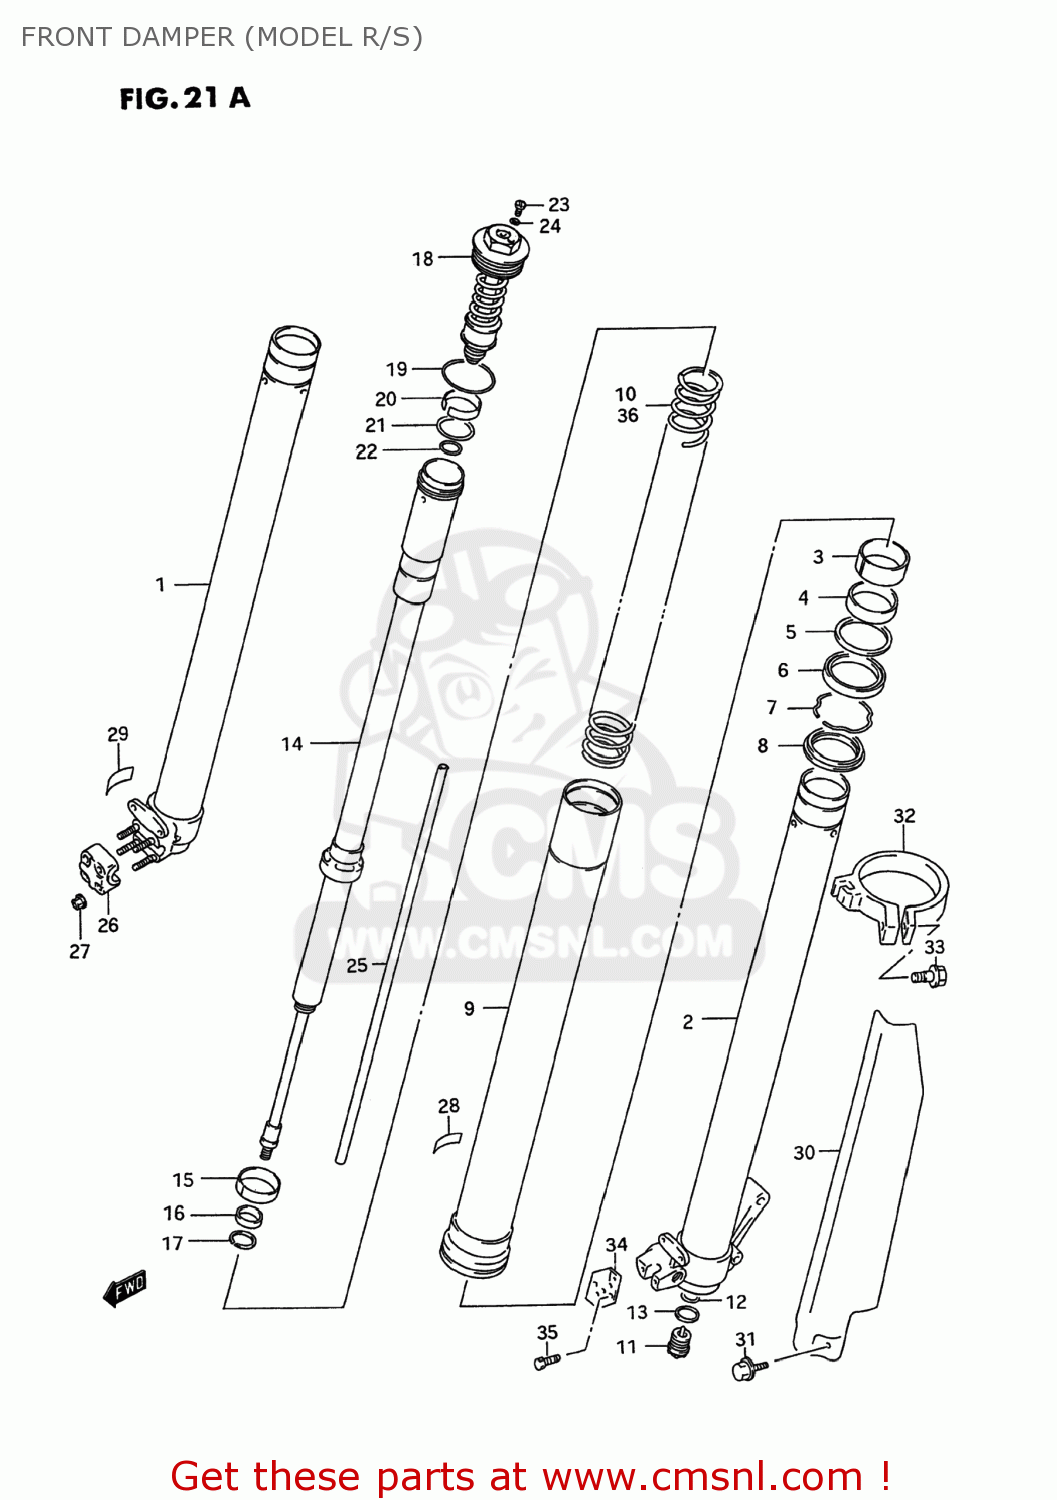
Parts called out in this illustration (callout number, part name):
1	TUBE,INNER,RIGHT
2	TUBE,INNER,LEFT
3	BUSH,SLIDE
4	BUSH,GUIDE
5	SPACER,SEAL
6	SEAL,OIL
7	RING,OIL SEAL STOPPER
8	SEAL,DUST
9	TUBE,OUTER
10	SPRING,MAIN
11	BOLT,CTR
12	GASKET (NAS)
13	O RING,CTR BOLT
14	DAMPER,CARTRIDGE
15	BUSH,DAMPER SLIDE
16	VALVE,OIL LOCK
17	RING,VALVE STOPPER
18	BOLT,FORK
19	O RING
20	BUSH,FORK BOLT SLIDE
21	O-RING,FORK BOLT,CENTER
22	O-RING,FORK BOLT,LOWER
23	BOLT,PLUG
24	O RING,PLUG
25	ROD,PUSH
26	HOLDER,AXLE,R
27	NUT
28	LABEL
29	LABEL
30	PROTECTOR ,RH.
31	BOLT
32	GUIDE,FORK PROTECTOR
33	BOLT
34	GUIDE,HOSE,L
35	BOLT
36	SPRING,MAIN
